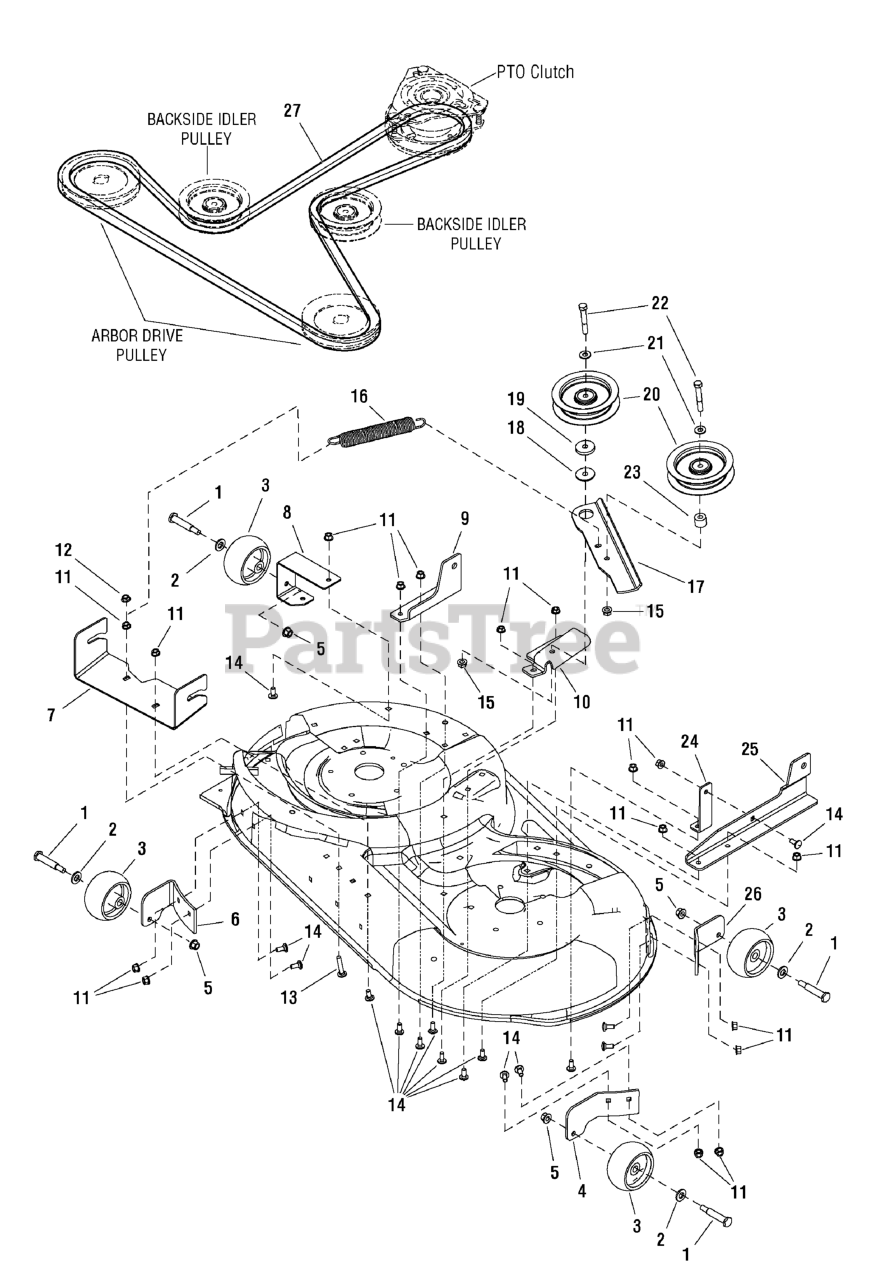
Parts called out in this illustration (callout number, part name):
1	BOLT, Shoulder (Gauge Wheel) 3/8-16 x 2.781 x 3/4
2	WASHER, .51 ID x 1 OD x 1/10 THK
3	GAUGE WHEEL
4	BRACKET, Gauge Wheel, Front, Left
5	NUT, Hex Flange, 3/8-16 ESNA
6	BRACKET, Gauge Wheel R.H. Front
7	HITCH, Mower Front
8	BRACKET, Gauge Wheel, Rear, Right
9	SUPPORT, Mower Rear, Right
10	BRACKET, Fixed Idler
11	NUT, Hex Flange Whiz Lock, 5/16-18
12	NUT, Hex Two-Way Lock, 5/16-18
13	BOLT, Carriage, 5/16-18 x 1-3/4, G5
14	BOLT, Carriage, 5/16-18 x 3/4, G5
15	NUT, Hex Flange Whiz Lock, 3/8-16
16	SPRING, Extension
17	ARM, Idler
18	SPACER, Powdered Metal
19	WASHER, 3/8, .41 ID x 1-1/2 OD x 1/4 THK
20	PULLEY, Idler, 4 OD x .378 ID x 1
21	WASHER, 3/8
22	CAPSCREW, Hex Head, 3/8-16 x 2-1/4, G5
24	BRACE, Mower Support
25	SUPPORT, Mower Rear Left
26	SUPPORT, Gauge Wheel, LH
27	V-BELT, A-Wedge
